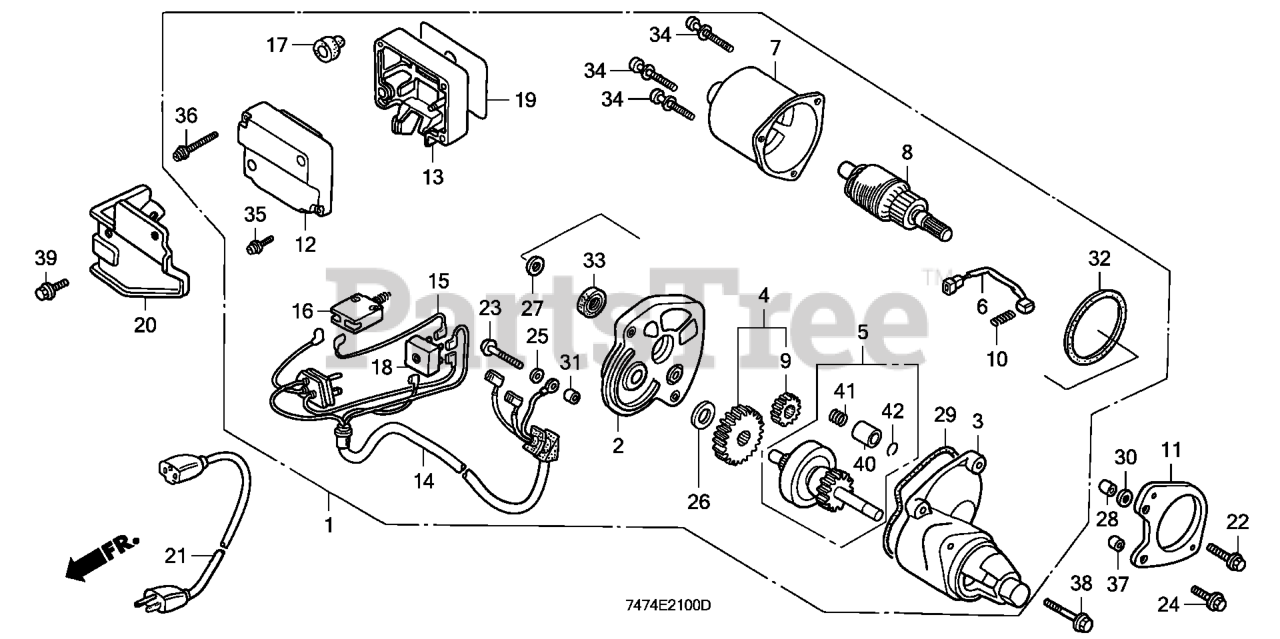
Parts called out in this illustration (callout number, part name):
11	BRACKET, STARTER MOTOR
21	WIRE, POWER Use up to Engine SN 2056819.
22	BOLT, FLANGE (6X32)
24	BOLT, FLANGE (6X25) Use up to Engine SN 2056819.
28	PIN, DOWEL (8X19)
30	COLLAR (8X5)
37	PIN A, DOWEL (8X14)
